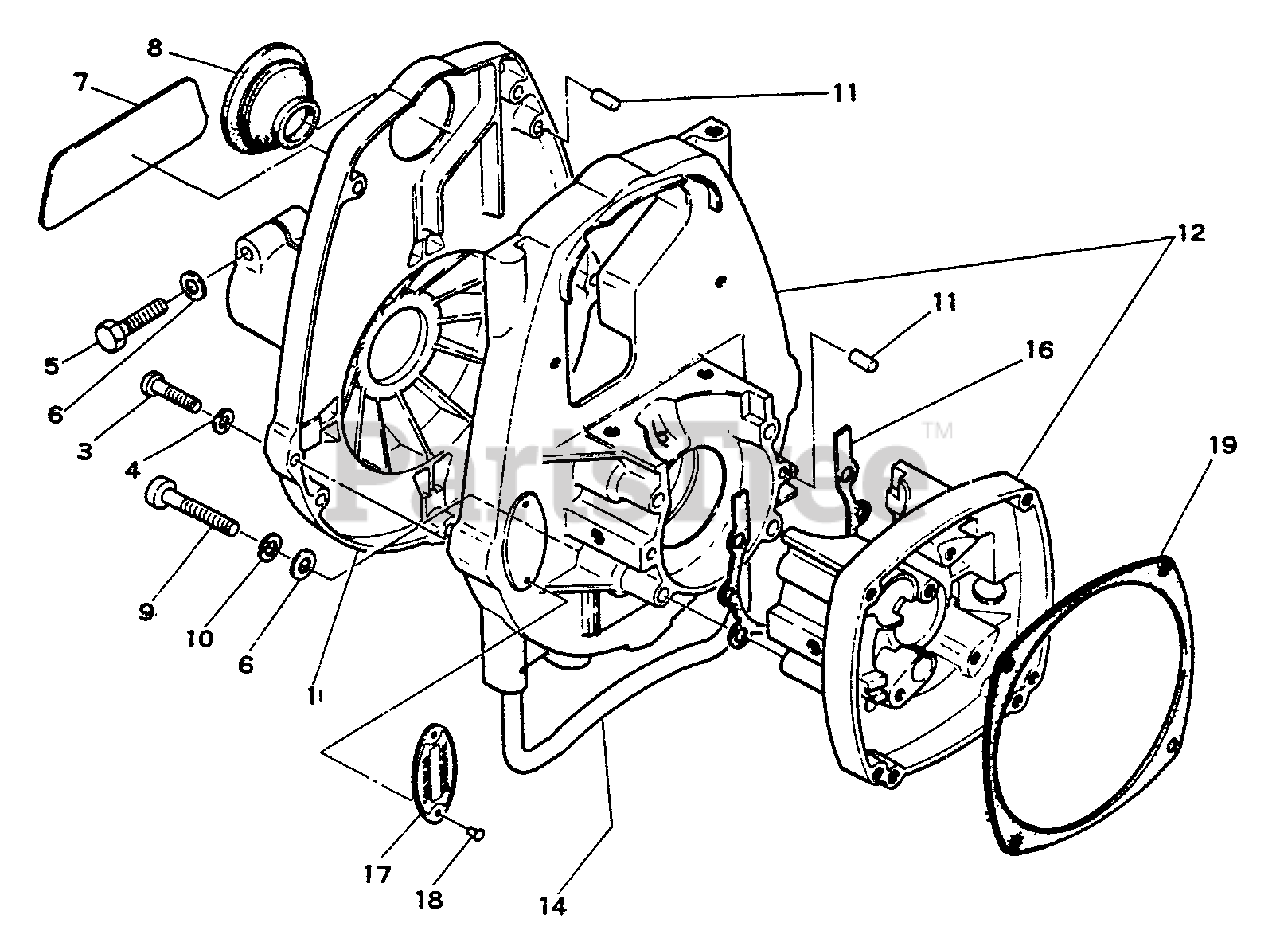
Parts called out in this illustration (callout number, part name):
1	CASE, FAN
3	SCREW - 4X18
4	WASHER - 4
5	BOLT - 5X20
6	WASHER - 5
7	PLATE, MODEL
8	SEAL, DUST
9	SCREW - 5X30
10	LOCKWASHER - 5
11	PIN - LOCATING
12	CRANKCASE KIT
14	STAND
16	GASKET, CRANKCASE
17	PLATE, MODEL
18	RIVET
19	GASKET, STARTER
